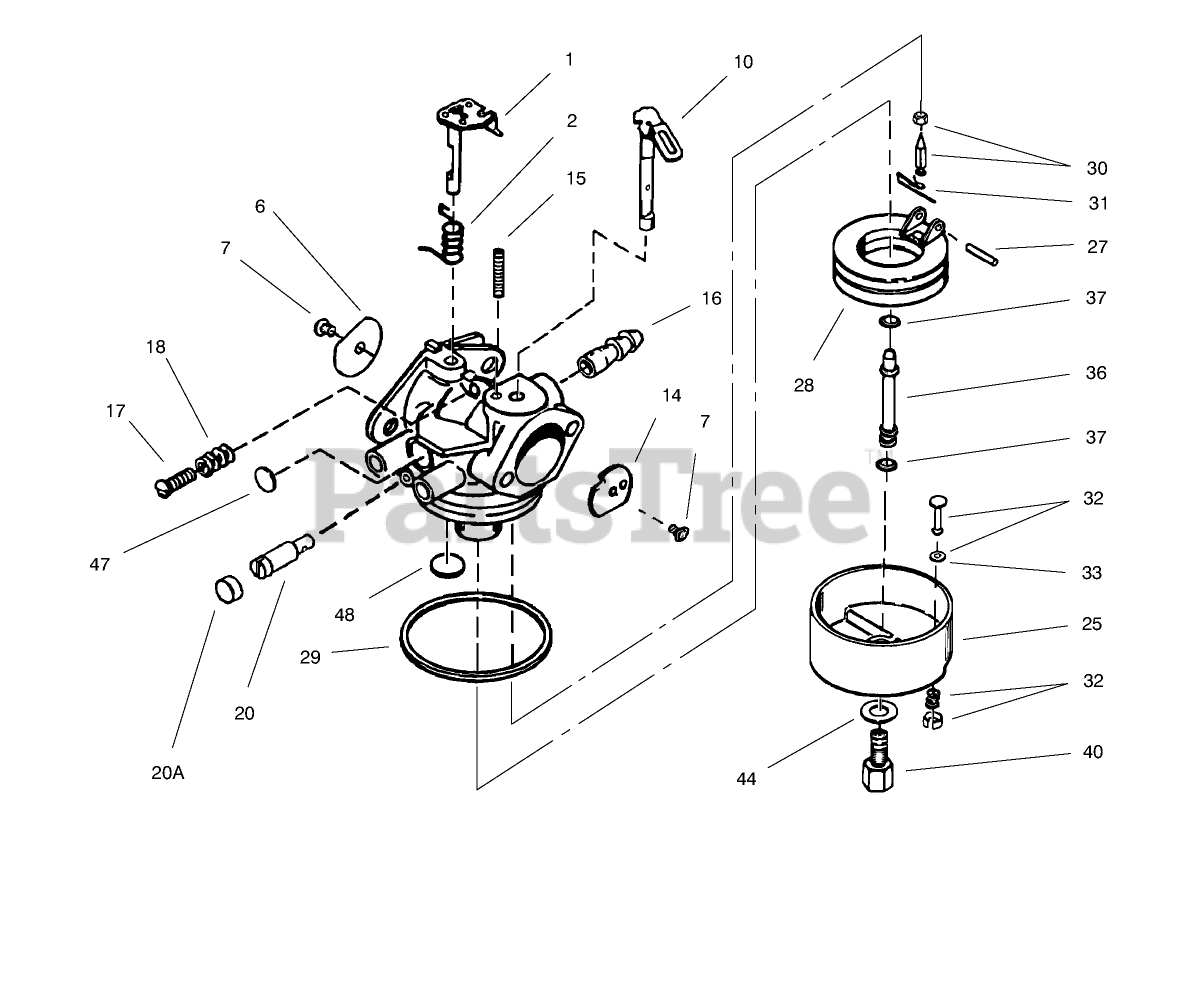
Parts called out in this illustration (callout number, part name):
1	Throttle Shaft and Lever ASM
2	Spring-Return, Throttle
6	Shutter-Throttle
7	Screw-Shutter
10	Choke Shaft and Lever ASM
14	Shutter-Choke
15	Spring-Positioning, Choke
16	Fitting-Fuel
17	Screw-Throttle Crack Screw / Idle Speed
18	Spring-Tension
20	Screw-Restrictor, Idle
21	Cap-Screw, Idle Restrictor
25	Float Bowl Asm. (Incl. Ref. # 32, 33)
27	Shaft-Float
28	Float
29	O Ring-Bowl, Float
30	Inlet Needle, Seat Clip Assy. (Incl. No. 13)
31	Clip-Spring
32	Bowl Drain ASM
33	Gasket-Plunger, Drain
36	Tube-Nozzle, Main
37	O-Ring
40	Nut-High Speed, Bowl
44	Washer-Bowl Nut
47	Plug-Welch, Idle Mixture Well
48	Plug-Welch, Atmospheric Vent
